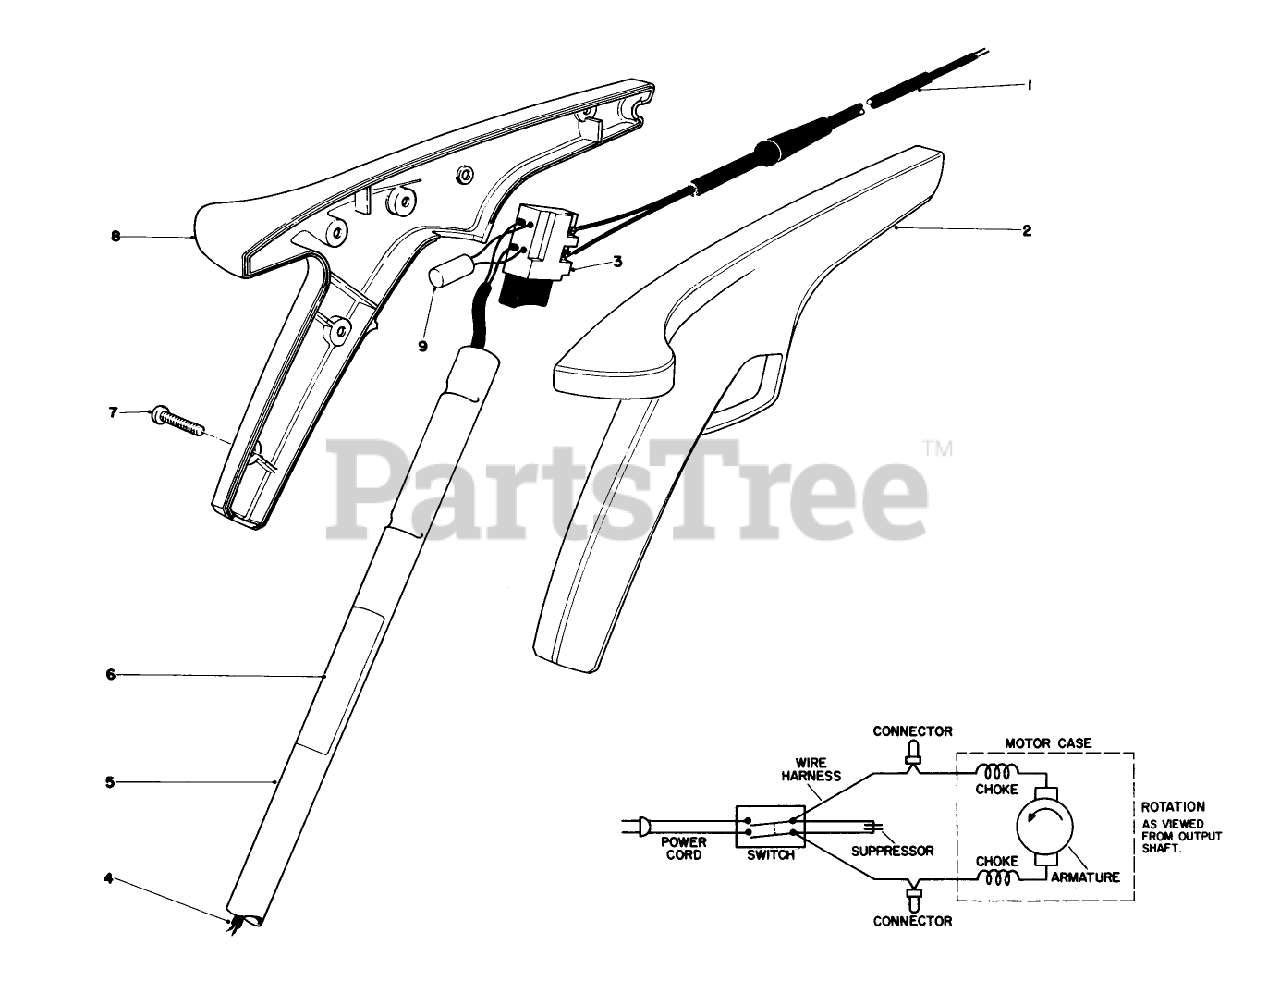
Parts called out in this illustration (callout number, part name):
1	Power Cordset
2	Left Hand Grip
3	Switch
4	Wiring Harness
5	Handle Tube
6	Caution Decal
7	Screw
8	Right Hand Grip
9	Suppressor
